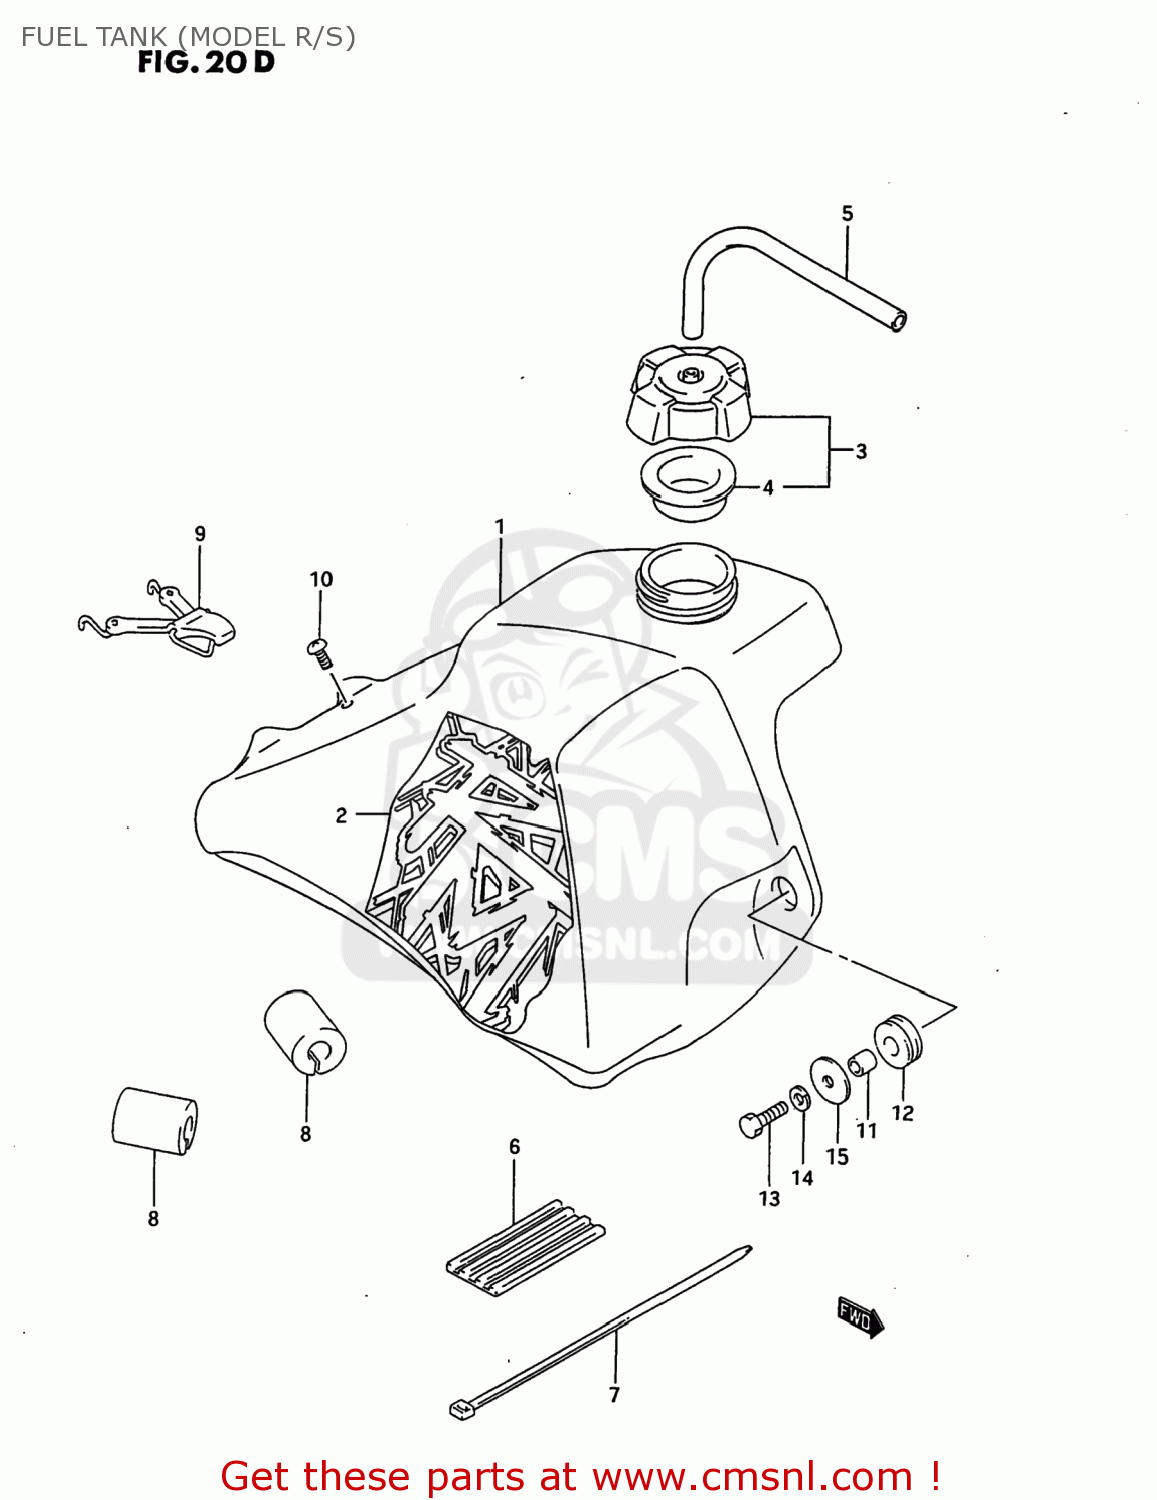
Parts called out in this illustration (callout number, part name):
1	TANK SET,FUEL
2	EMBLEM
3	CAP SET,FUEL TANK
4	GASKET,CAP (NAS)
5	HOSE
6	CUSHION,FUEL TANK UPR FR
7	CLAMP
8	CUSHION,FUEL TANK UPR RR
9	BAND,FUEL TANK RR
10	SCREW
11	SPACER (6.8X10X11.5)
12	CUSHION
13	BOLT
14	WASHER,LOCK
15	WASHER (6.5X24X1.6)
